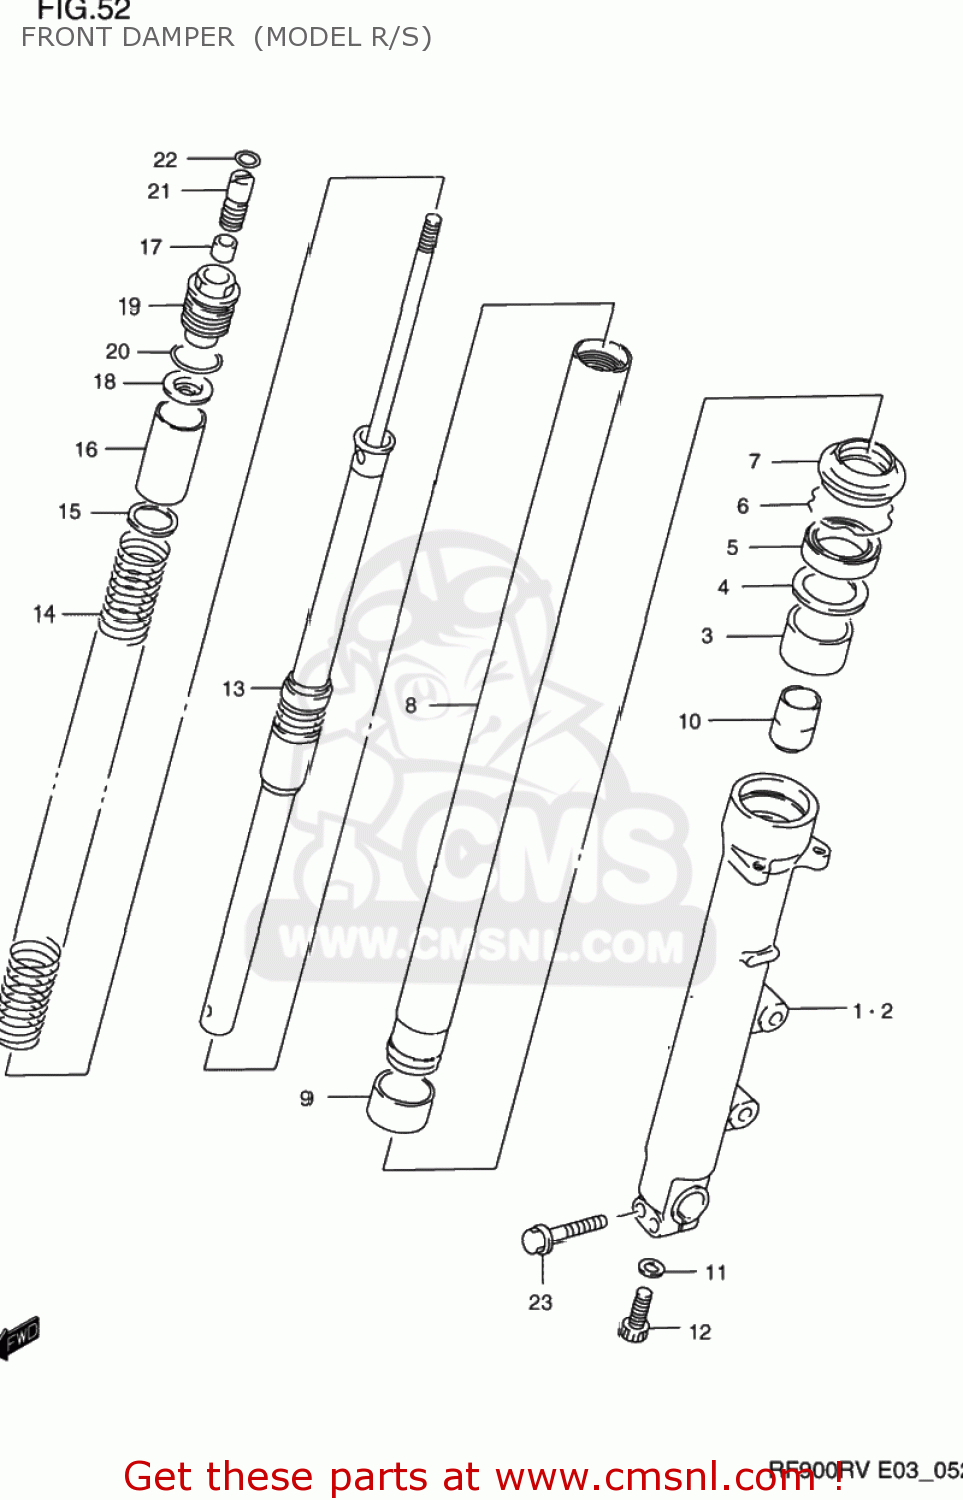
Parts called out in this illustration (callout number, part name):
1	TUBE,OUTER,R
2	TUBE,OUTER,L
3	BUSH,GUIDE
4	SPACER,SEAL
5	SEAL,OIL
6	CIRCLIP,FORK OIL SEAL
7	SEAL,DUST
8	TUBE,INNER
9	BUSH,SLIDE
10	PIECE,OIL LOCK
11	GASKET (NAS)
12	BOLT(8X27)
13	DAMPER,FR
14	SPRING,MAIN
15	SEAT,SPRING LWR
16	COLLAR,SPRING(35X37X50)
17	NUT
18	SEAT,SPRING UPR
19	BOLT,FORK
20	O RING
21	ADJUSTER,SPRING
22	O RING
23	BOLT
